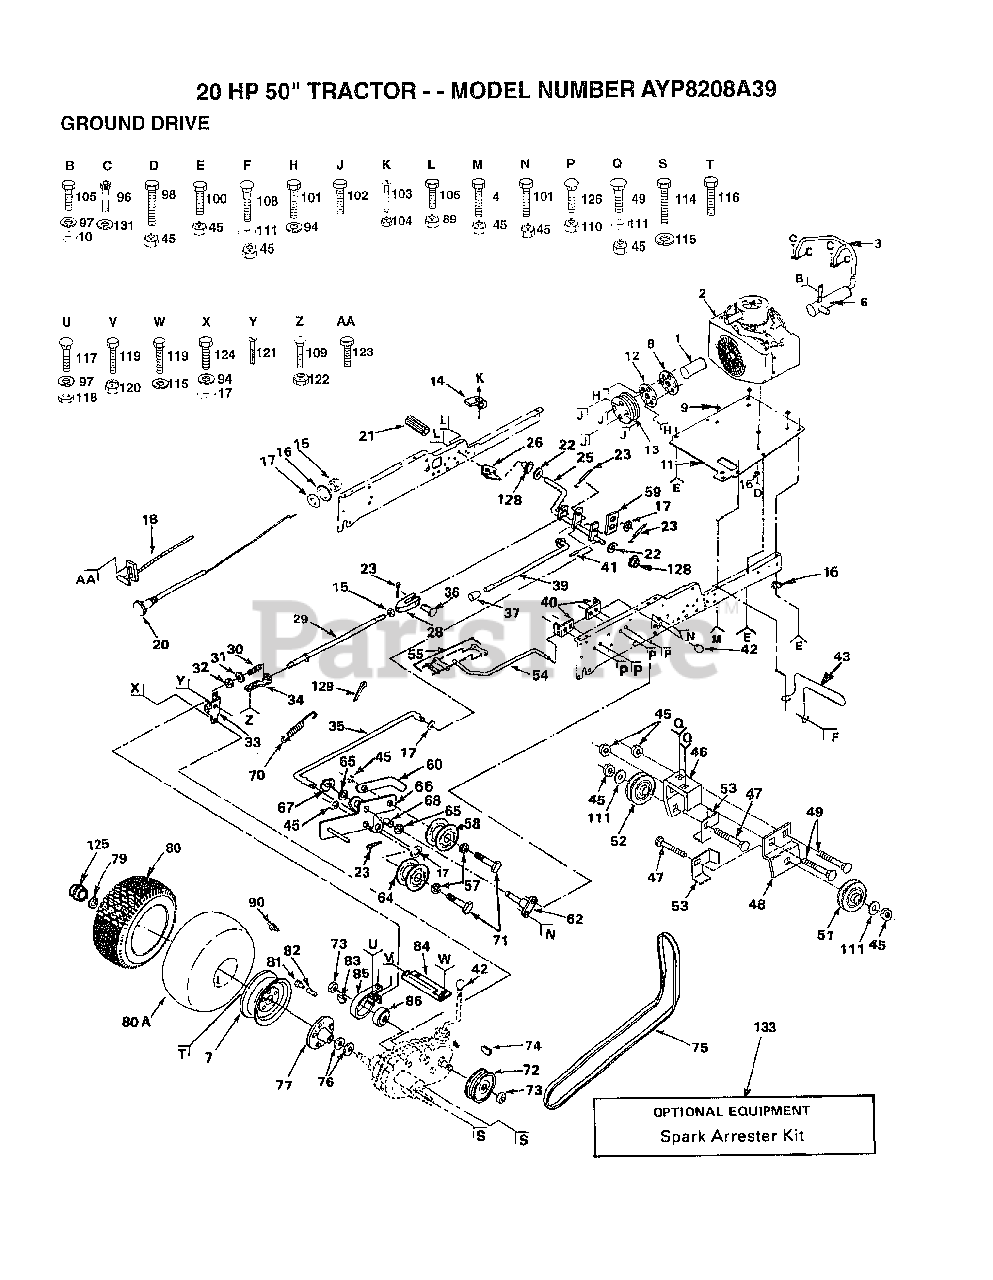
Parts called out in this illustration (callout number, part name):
3	EXHAUST TUBE T
4	"BOLT,HEX"
6	MUFFLER EXHAUST
8	CHAFF GUARD T
9	SPACER.ENGINE KOH
11	"ENG. T, BASE"
12	ADAPTER T
14	ACT-SWITCH T
16	LOCKWASHER
17	WASHER
21	PEDAL COVER T
22	WASHER
25	SHAFT ASSY GT
26	BRKT SWITCH GT
28	YOKE GTV
29	BRAKE ROD T
30	SPRING T
31	WASHER
33	BRAKE BRKT ASSY T
34	GUIDE ROD T
35	ROD CLUTCH GTV
36	CLEVIS PIN T
37	PLUNGER CAP T
39	BRAKE ROD
40	ROD BRACKET GT
41	ROLL PIN STD
42	KNOB
43	GUARD MUFFLER HYT
47	BOLT
48	BRKT IDLER FLAT
49	BOLT
51	IDLER-FLAT T
52	PULLEY V IDLR GTV
53	GUARD BELT
54	ROD SHIFT HI LO
55	CONNECTING LINK
57	WASHER
59	RETAINER SPRING
60	RETAINER BELT
62	BRACKET ASSY GTV
65	WASHER T
66	BRACKET CLUTCH
67	KLIP RING
68	"LY, BEARING"
70	SPRING EXT CLUTCH
73	NUT STD
75	BELT-V.98.5.GD.DV
76	WASHER T
79	KLIP RING
80A	TUBE.23X8/10-12
81	VALVE CAP
82	VALVE STEM LT
85	BRAKE BAND ASM
86	BRAKE DRUM T
90	ZERK FITTING M
94	LOCKWASHER
96	SCREW
97	LOCKWASHER
101	BOLT
102	SCREW
103	SCREW
108	BOLT.3/8-14X1.25
111	WASHER GT
114	BOLT
115	LOCKWASHER
117	BOLT T
119	BOLT
120	NUT GTV
121	SCREW
123	SCREW LT
125	CAP-HUB GT
126	BOLT
128	NYLINER T
133	SPARK ARREST KIT
